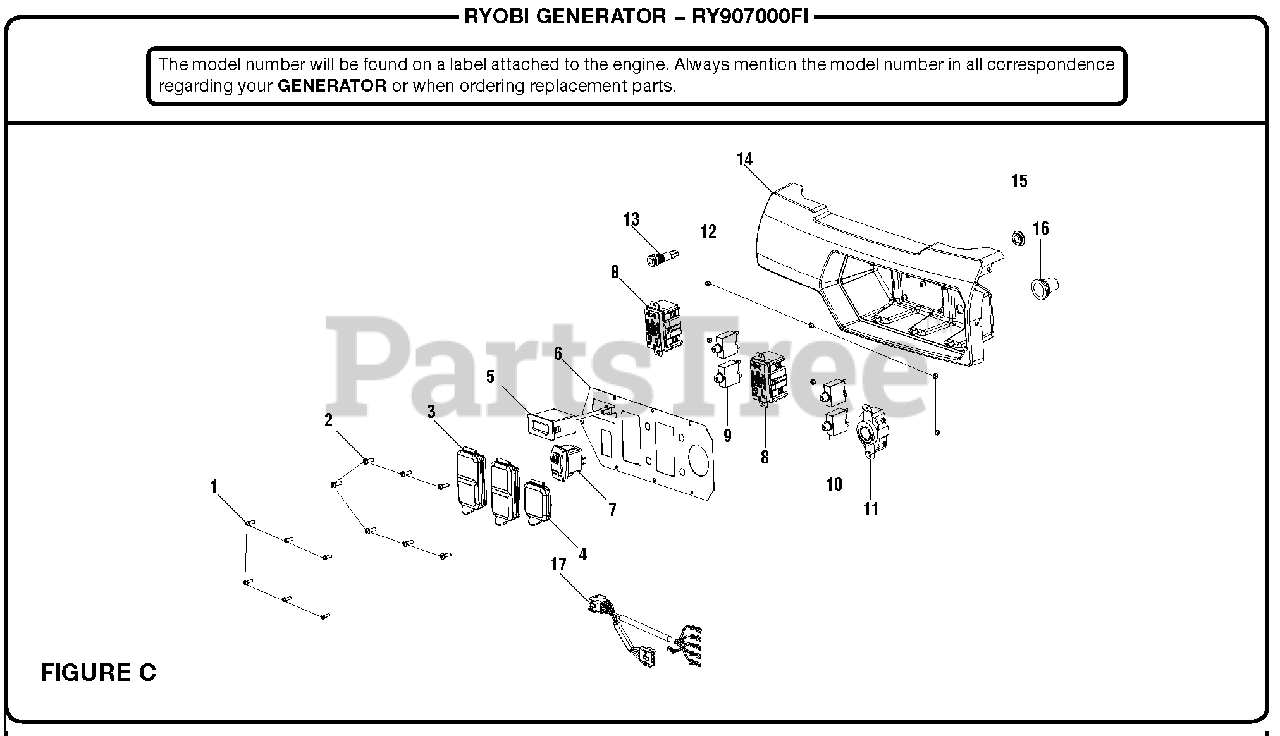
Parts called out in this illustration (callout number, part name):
1	Screw (6-20 x 5 mm)
2	Screw (8-18 x 1/2 in.)
3	GFCI Receptacle Cover
4	Receptacle Cover (30 Amp)
5	Digital Display
6	Faceplate
7	Start/Stop Switch
8	120 Volt GFCI Receptacle
9	Circuit Breaker (20 Amp)
10	Circuit Breaker (30 Amp)
11	120 Volt Twist Lock Receptacle (30 Amp)
12	Lock Nut (#6-32)
13	12V LED w/Resistor Indicator
14	Control Box
16	Rubber Boot
17	Wiring Harness
